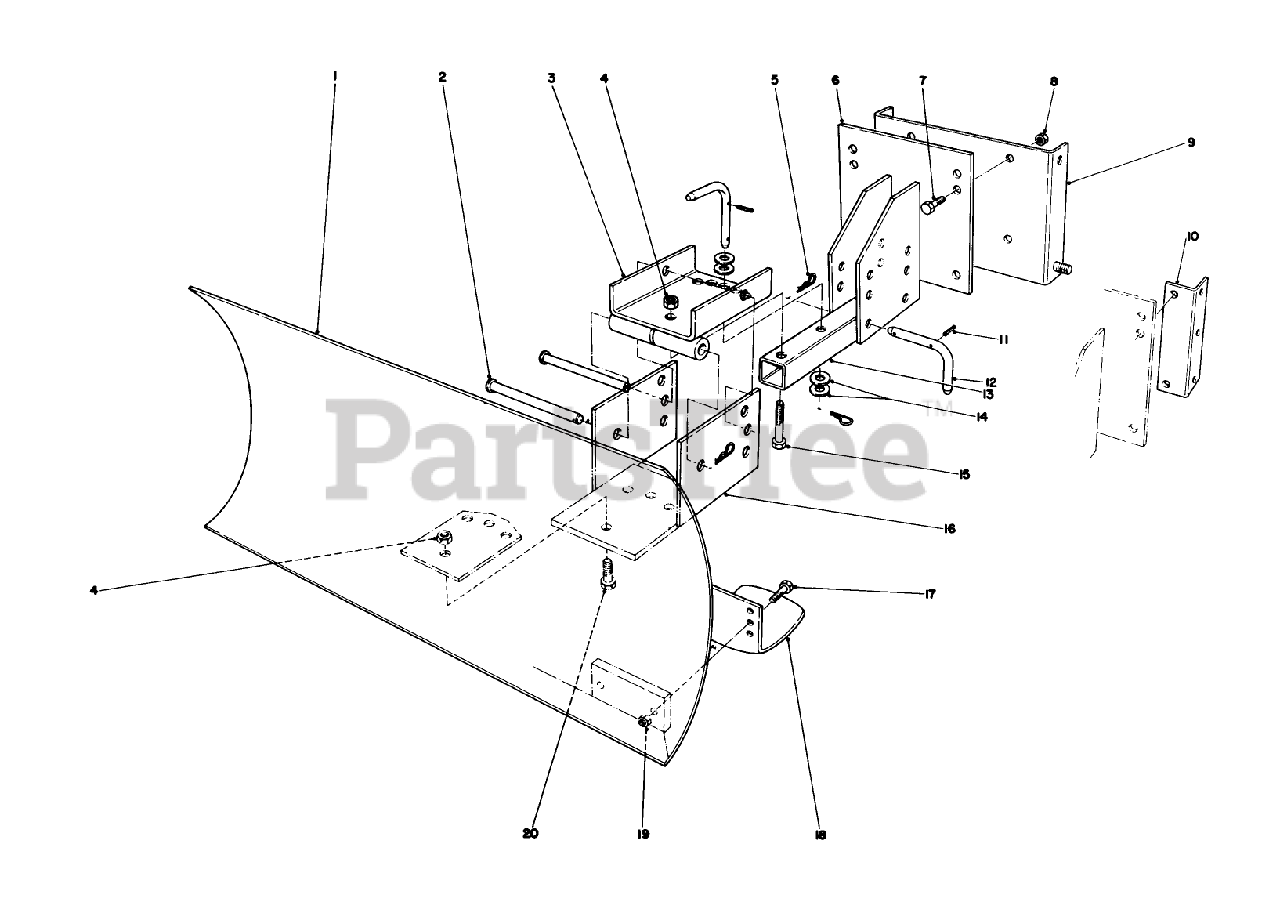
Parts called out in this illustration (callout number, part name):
1	Blade
2	PIN-CLEVIS
3	Swivel Bracket
4	1/2-13 CONELOCK NUT
5	PIN-HAIR
6	Mounting Plate
7	SCREW-HH
8	NUT-LOCK, CONE
9	Mounting Plate (Used with 826 & 1132 Units only)
10	Mounting Rail (used with 421 units only)
11	PIN-SPRING
12	Pivot Pin (Incl. Ref. #11)
13	Blade Tongue
14	WASHER-FLAT
15	SCREW-HH
16	Blade Adjustment
17	SCREW-HH
19	NUT-LOCK, CONE
20	SCREW-HH
